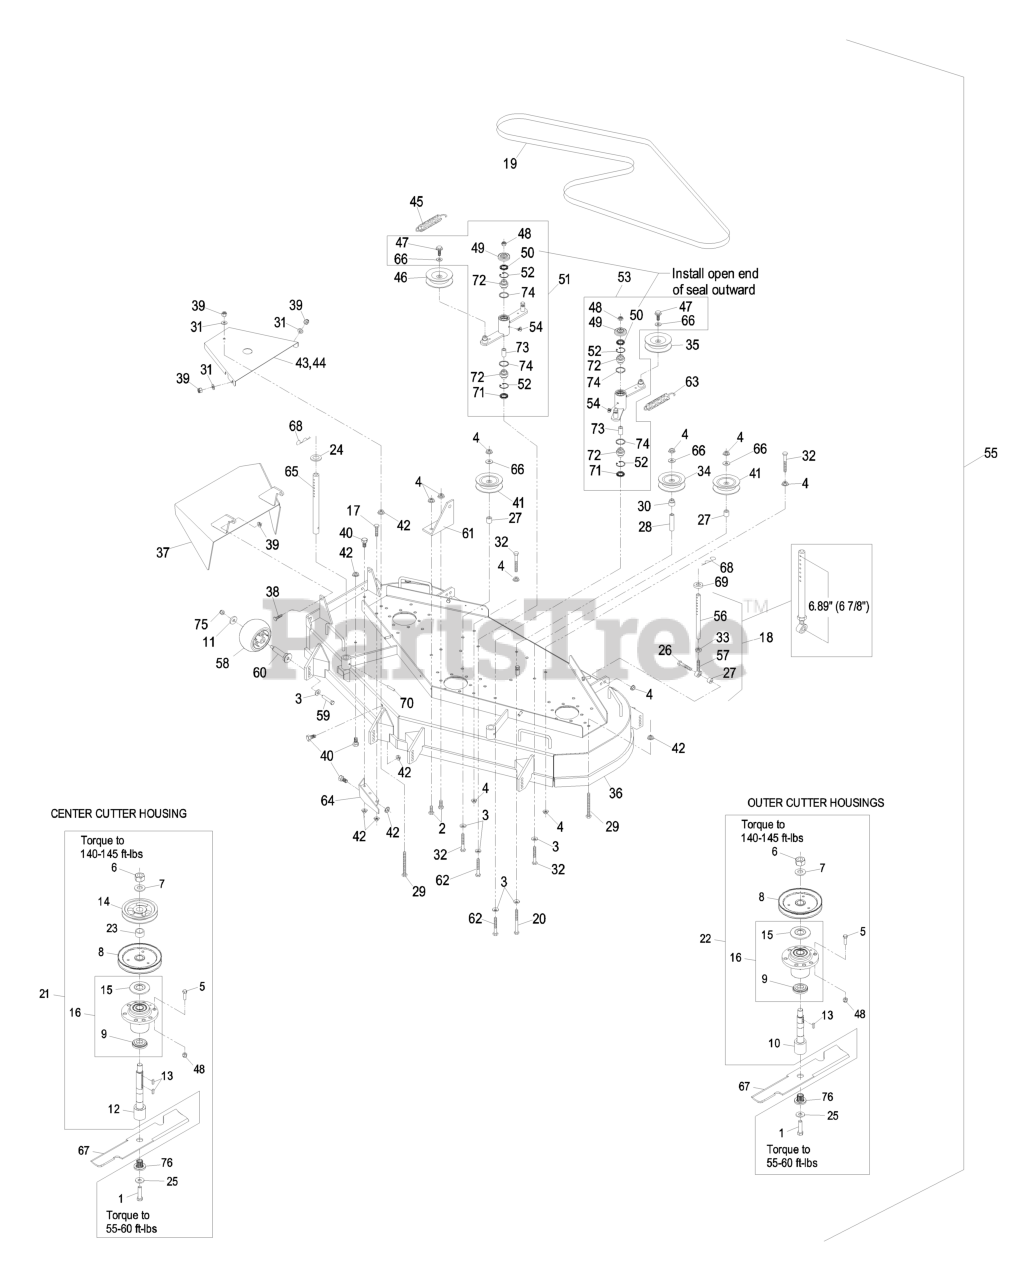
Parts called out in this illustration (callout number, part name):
1	SCREW-HH
2	SCREW-HH
3	WASHER-BELLEVILLE
4	NUT-HHF, WHIZ
5	SCREW-HH
6	NUT-HH
8	SHEAVE,BLADE DRIVE 6.30
9	SPACER-GUARD, BOTTOM
10	KIT, SPLINED SPINDLE 103-
12	KIT, SPLINED SPINDLE 103-
14	SHEAVE,BLADE DRIVE
15	GUARD-BEARING, TOP
16	KIT, CUTTER HOUSING
17	SCREW-HH
19	BELT,MULE DRIVE
20	SCREW-HH
21	ASM, CUTTER HSG FMD604CTR
22	ASM, CUTTER HSG COMPLETE
23	SPACER,TUBE
24	SPACER-DECK SUPPORT
25	WASHER-SPRING
26	SCREW-HH
28	SPACER-ANCHOR, CLUTCH
29	BOLT,TAP HH
30	BUSHING,IDLER
31	WASHER-FLAT
32	BOLT-CARR
33	NUT-HEX
34	PULLEY-IDLER
35	PULLEY-IDLER
36	ASM, DECK W/DECALS FMD604
37	WLD,CHUTE FMD604
38	SCREW-HH
39	NUT-LOCK, NI
40	SCREW-HH
41	IDLER,PULLEY
43	SHIELD,BELT RH
44	SHIELD,BELT LH
45	SPRING-EXTENSION
46	IDLER,PULLEY
47	SCREW-HHF
48	NUT-LOCK, NI
49	GUARD-TOP
50	SEAL-LIP, SINGLE
51	KIT, IDLER ARM W/BEARINGS
52	RING-SNAP
53	KIT, IDLER ARM W/BEARINGS
54	FITTING-GREASE, 90 DEG
55	Complete Deck Assy
56	LINK,SUPPORT
57	BALLJOINT
58	ROLLER-SCALP, ANTI
59	SCREW-HH
61	BRACKET,SPRING ANCHOR
62	SCREW-HH
63	SPRING-EXTENSION
64	WLD,BAFFLE DISCHARGE
65	ROD,DECK SUPPORT
66	WASHER-FLAT
68	PIN,HAIR COTTER
71	SEAL-LIP, DOUBLE
72	BEARING-SPHERICAL
73	BUSHING-LEVER, LIFT
75	NUT-LOCK, NI
76	BUSHING,SPLINED
